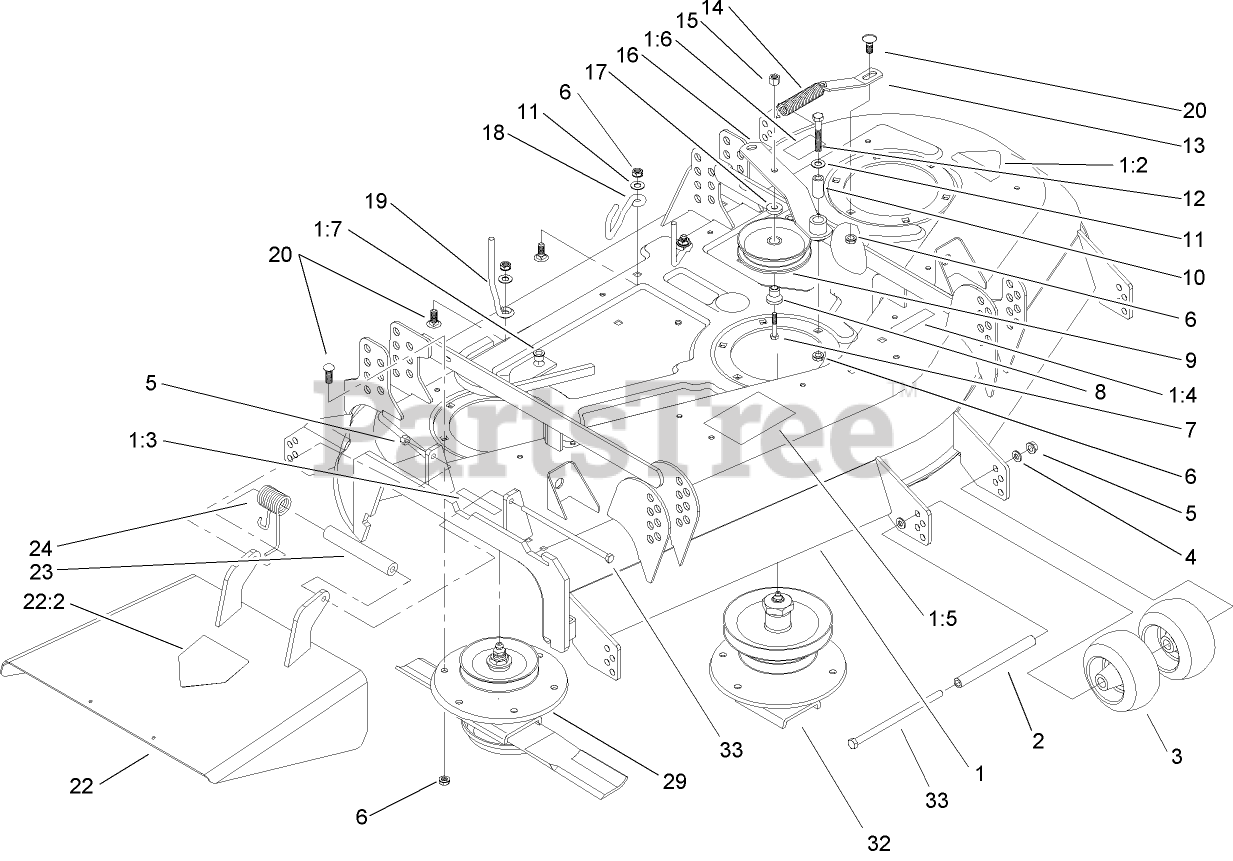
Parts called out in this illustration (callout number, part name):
1	52IN DECK ASM
1:2	DECAL-DANGER
1:3	DECAL-DANGER
1:4	DECAL-DANGER
1:5	DECAL-DANGER, THROWN OBJECT
1:6	DECAL-TORQUE
1:7	INSERT-NUT
2	SPACER-WHEEL
3	WHEEL-GAGE
4	WASHER-PLAIN
5	NUT-LOCK, NI
6	NUT-HF
7	SCREW-HH
8	BUSHING-PULLEY
9	PULLEY-IDLER
10	SLEEVE
11	WASHER-FLAT
12	SCREW-HH
13	PLATE-SPRING
14	SPRING-EXTENSION
15	NUT-HEX
16	IDLER ARM ASM
17	WASHER-FLAT
18	GUIDE-BELT
19	ROD-BELT
20	SCREW-CARR
22	Deflector ASM
22:2	DECAL-DANGER
23	SPACER
24	SPRING-TORSION
29	SPINDLE AND BLADE ASM
32	CENTER SPINDLE AND BLADE ASM
33	SCREW-HH
